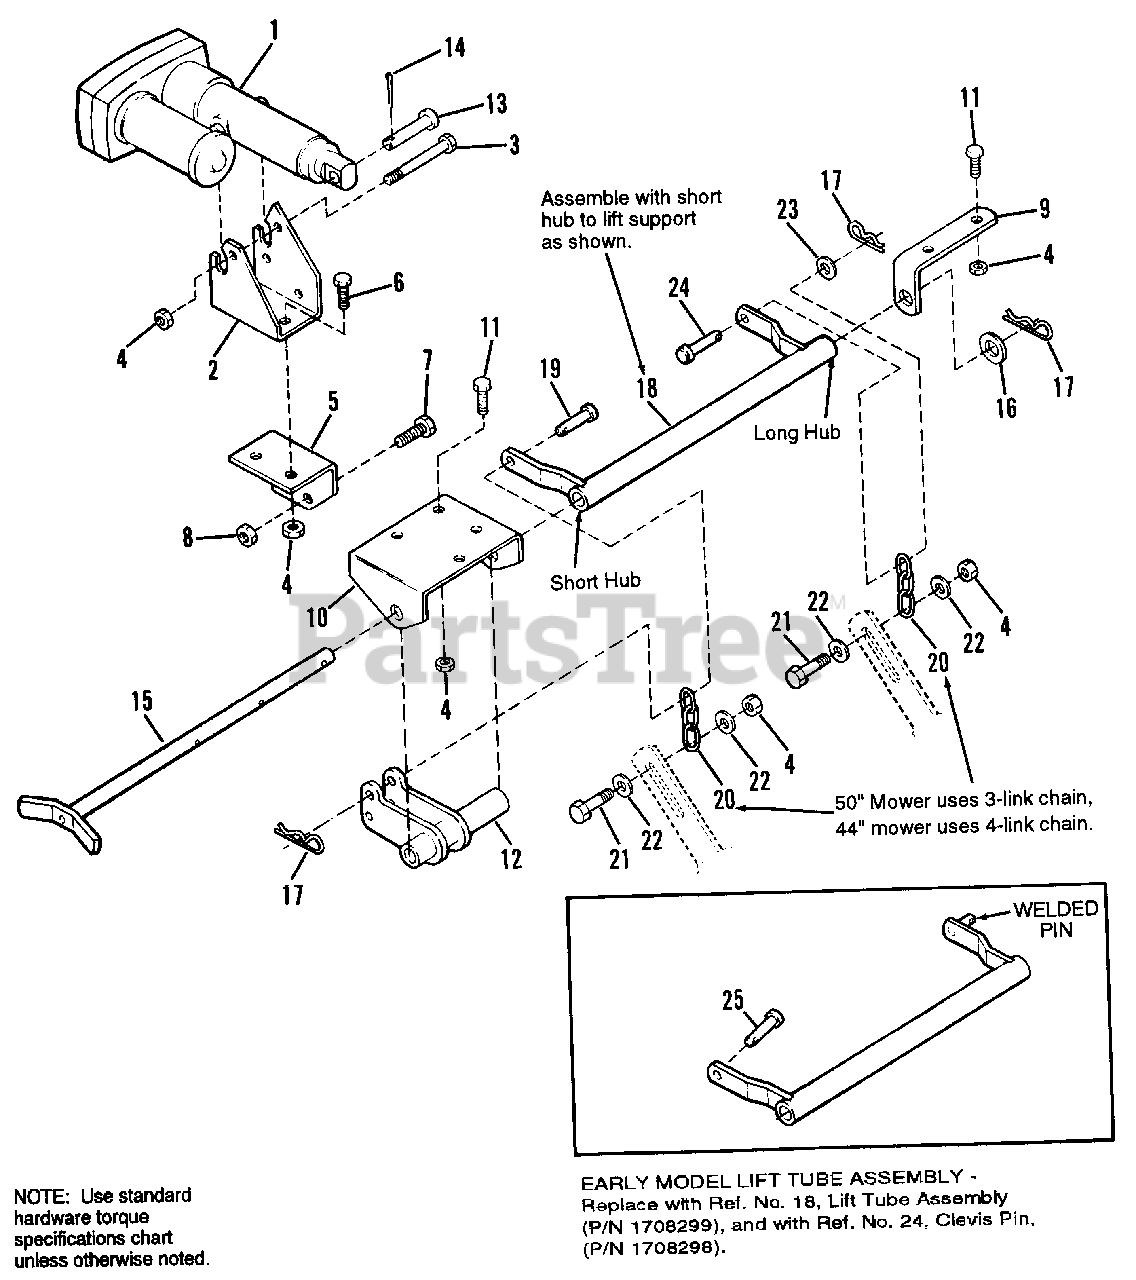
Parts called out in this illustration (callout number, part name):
1	POWER LIFT ASSY. (See next page for service parts)
2	BRACKET, Actuator
3	CAPSCREW, Hex, 5/16-18 x 3-1/4
4	NUT, Hex, Lock, Esna, 5/16-18
5	SUPPORT, Actuator
6	CAPSCREW, Hex, 5/16-18 x 1
7	CAPSCREW, Hex, Whizlock 3/8-16 x 1
8	NUT, Hex, Lock, Esna, 3/8-16
9	LIFT, Pivot Bracket
10	SUPPORT, Lift
11	CAPSCREW, Hex, 5/16-18 x 7/8
12	LIFT ARM ASSY.
13	PIN
14	PIN, Cotter
15	SHAFT ASSY.
16	WASHER, Plain
17	CLIP, Hair Pin (Large) (Qty. 3 on early models)
18	LIFT TUBE ASSY. (See note on illustration)
20	CHAIN, 3-Link
20	CHAIN, 4-Link
21	CAPSCREW, Hex, 5/16-18 x 1-1/2
22	WASHER, Plain
23	WASHER, Plain
24	PIN, Clevis
25	PIN, Clevis (Early models only)
